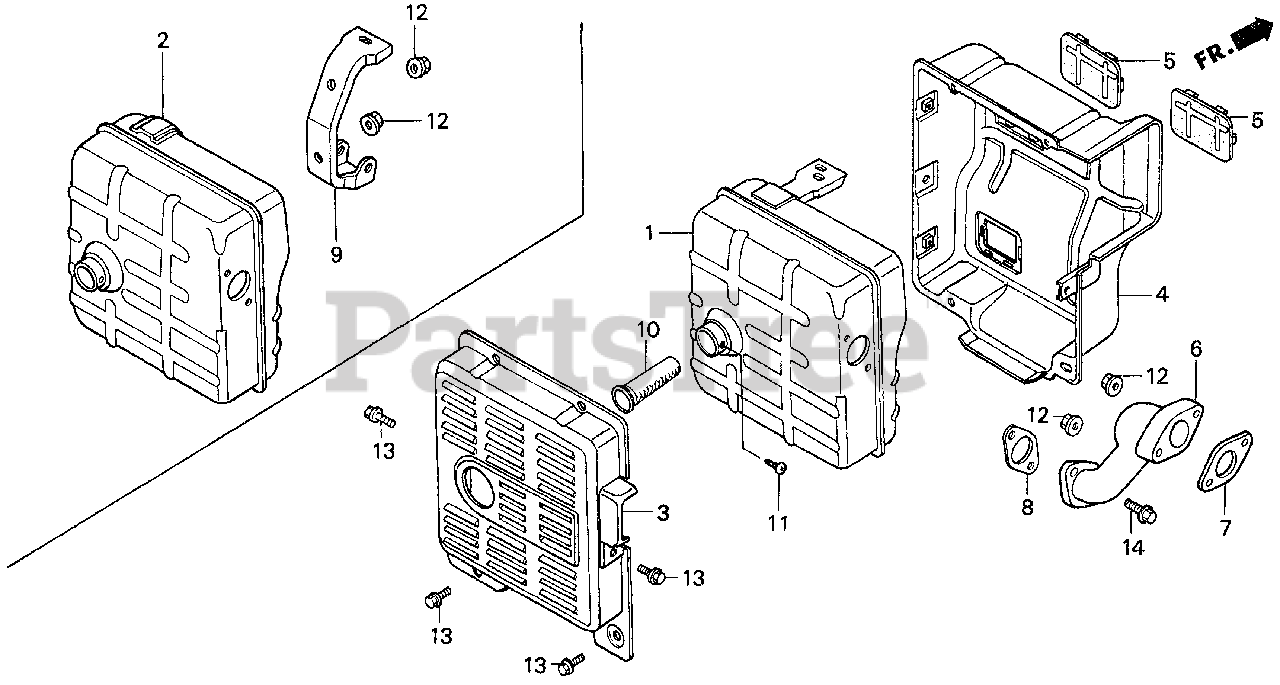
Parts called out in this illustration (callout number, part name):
2	MUFFLER (TSURUMI)
3	PROTECTOR, MUFFLER (OUTER)
4	PROTECTOR, MUFFLER (INNER)
5	SEAL, MUFFLER PROTECTOR
6	PIPE, EX.
7	GASKET, EX. PIPE
8	GASKET, EX. PIPE
8	GASKET, EX. PIPE (WACKER)
9	STAY A, MUFFLER (TSURUMI)
10	ARRESTER, SPARK
11	SCREW, TAPPING (4X8)
12	NUT, FLANGE (8MM)
13	BOLT, FLANGE (6X10)
14	BOLT, FLANGE (8X20)
